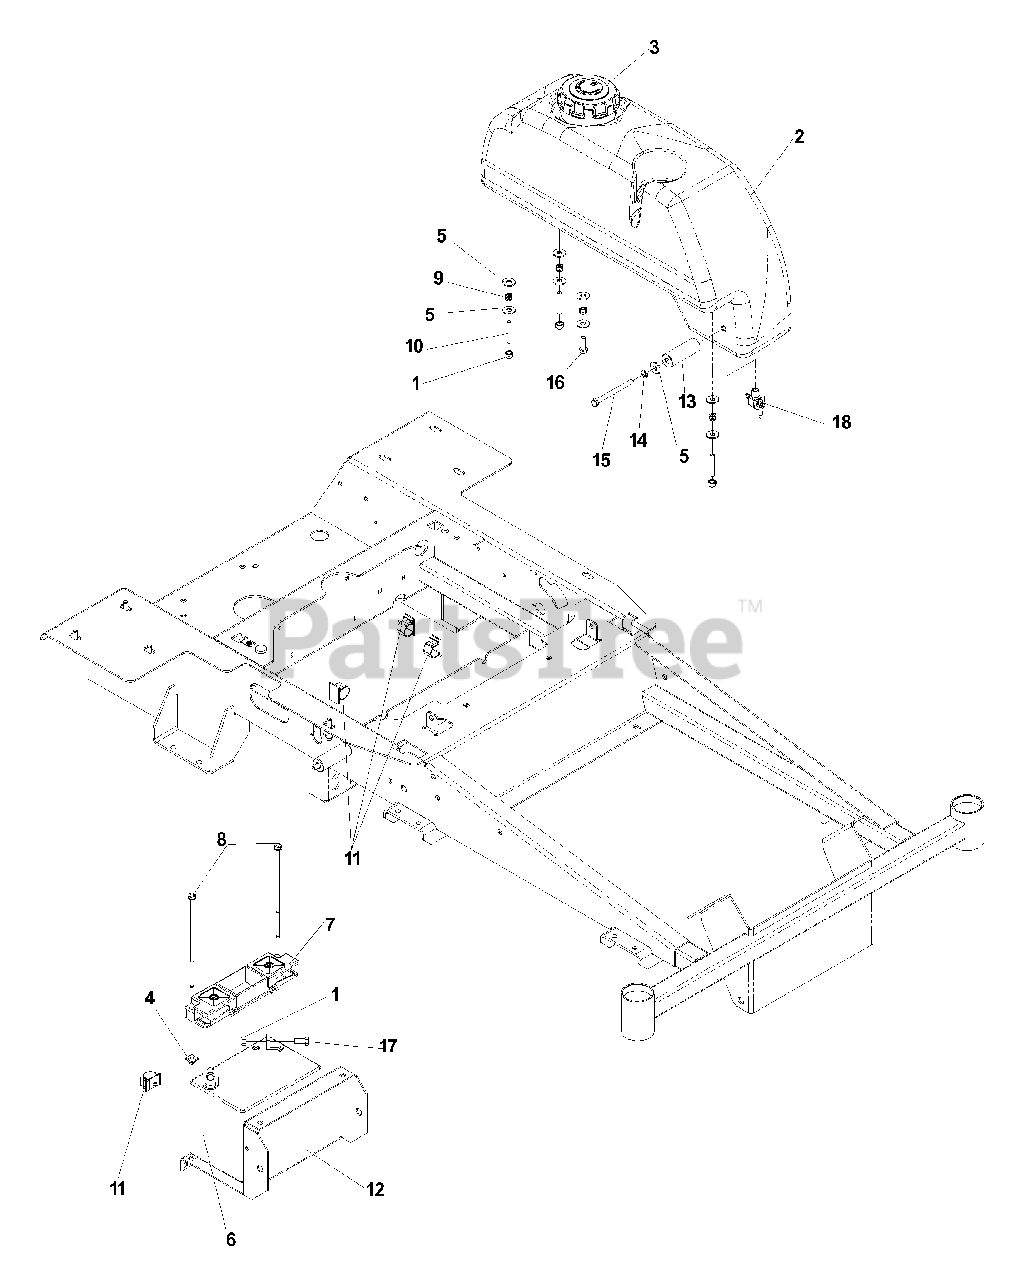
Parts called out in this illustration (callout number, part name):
1	NUT, 5/16-18, NYLOC
2	FUEL TANK, LEFT
3	FUEL CAP
4	PUSH NUT, NYLON
5	WASHER, 5/16
6	BATTERY, DRY
7	BATTERY HOLD DOWN
8	BOLT, 1/4 X 7 1/2, SPEC.
9	SPRING, TANK MOUNT
10	TANK STUD, FUEL, 5/16C
11	PUSH MOUNT, WIRE CLIP
12	BATTERY TRAY
13	TANK SPACER
14	LOCKWASHER, 5/16
15	HCS, 5/16-18 X 3 1/2, GR5
16	HCS, 5/16-18 X 1, GR5
17	HCS, 5/16-18 X 3/4, GR5
18	FUEL VALVE
